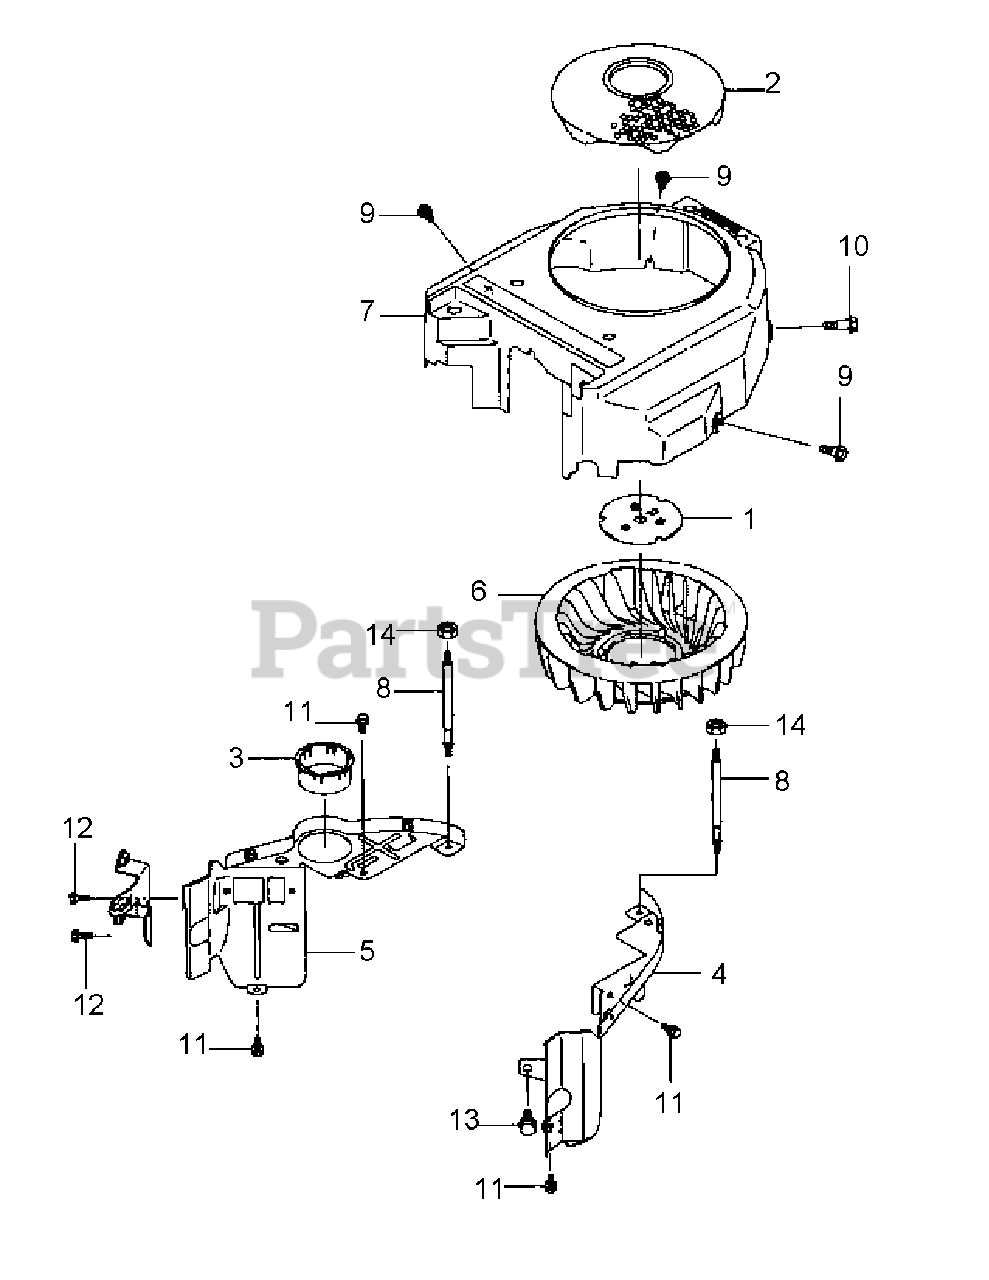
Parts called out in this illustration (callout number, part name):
4	ENGINE SHROUD
5	ENGINE SHROUD
6	FAN
10	BOLT
11	FLANGED BOLT
12	FLANGED BOLT
13	FLANGED BOLT
